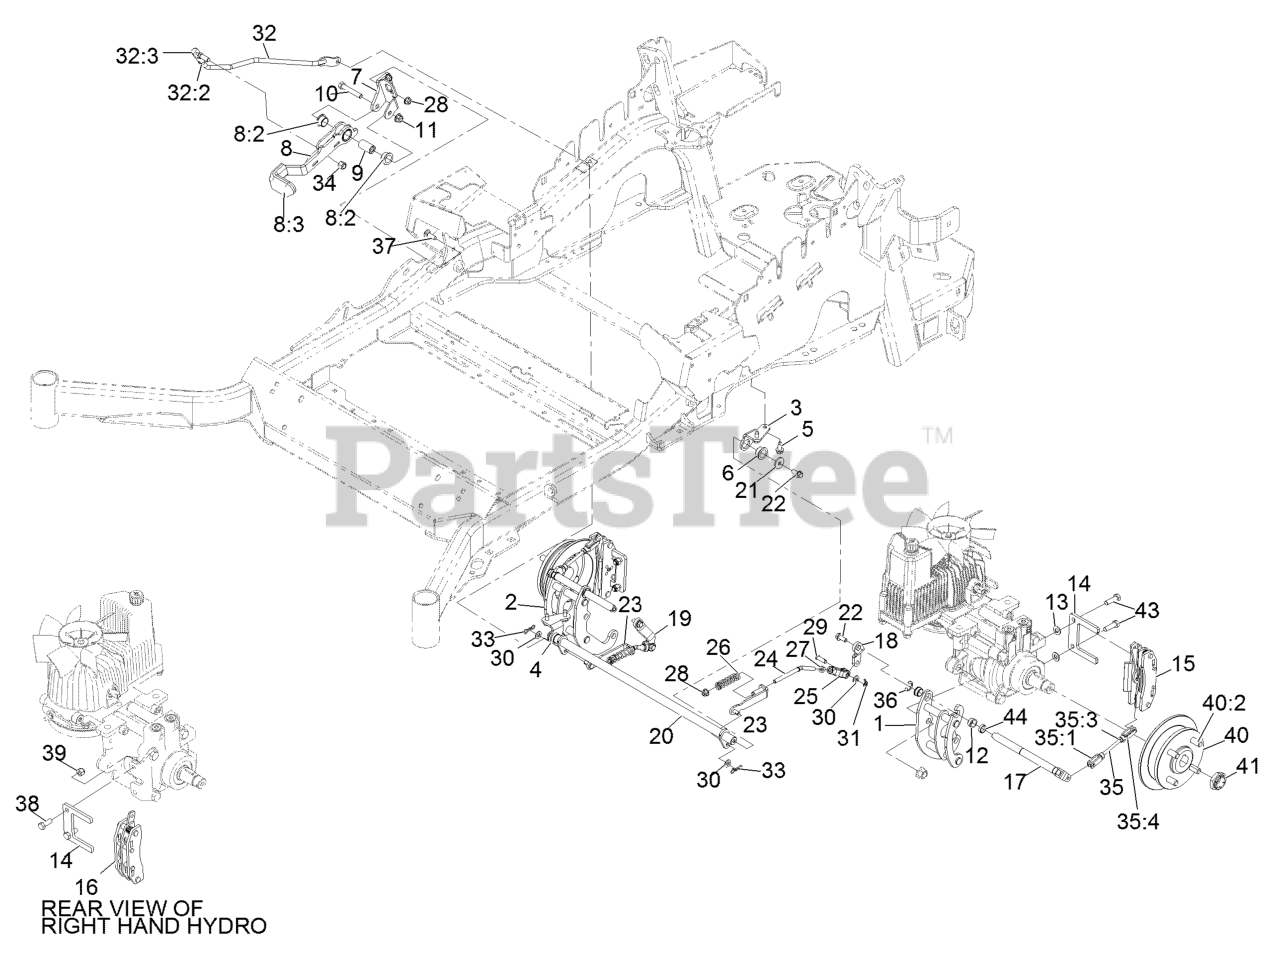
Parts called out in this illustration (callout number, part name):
1	MOUNT-BELLCRANK, LH
2	MOUNT-BELLCRANK, RH
3	MOUNT-PIVOT, LH
4	MOUNT-PIVOT, RH
5	Screw-HWH 5/16-18 X 3/4 Tf
6	BUSHING-FLANGE
7	BRACKET-MOUNT
8	BRAKE LEVER ASM
8:2	BUSHING-FLANGE
8:3	GRIP-LEVER
9	HANDLE-PIVOT, BRAKE
10	SCREW-HH
11	NUT-HF, NI
12	BUSHING
13	WASHER-FLAT
14	PLATE-MOUNT, BRAKE
15	CALIPER-BRAKE
16	CALIPER-BRAKE, RH
17	BELLCRANK
18	ARM-INNER, LH
19	ARM-INNER, RH
20	SHAFT-CROSS
21	WASHER-FLAT
22	SCREW-HHF
23	BRACKET-L
24	LINKAGE-MID
25	YOKE-OFFSET
26	SPRING-COMPRESSION
27	NUT-JAM
28	NUT-HF, NI
29	PIN-CLEVIS
30	WASHER-PLAIN
31	PIN-COTTER, LOCKING
32	FRONT LINKAGE ASM
32:2	END-TIE ROD, RH
32:3	NUT-HJ
33	PIN-COTTER, LOCKING
34	NUT-LOCK
35	REAR LINKAGE ASM
35:3	NUT-JAM
35:4	PIN-CLEVIS, SPRING
37	BOLT-CARR
38	SCREW-HH
39	NUT-LOCK, NI
40	WHEEL HUB ASM
40:2	STUD-WHEEL
41	LOCKNUT
43	SCREW-LOCK, PATCH
